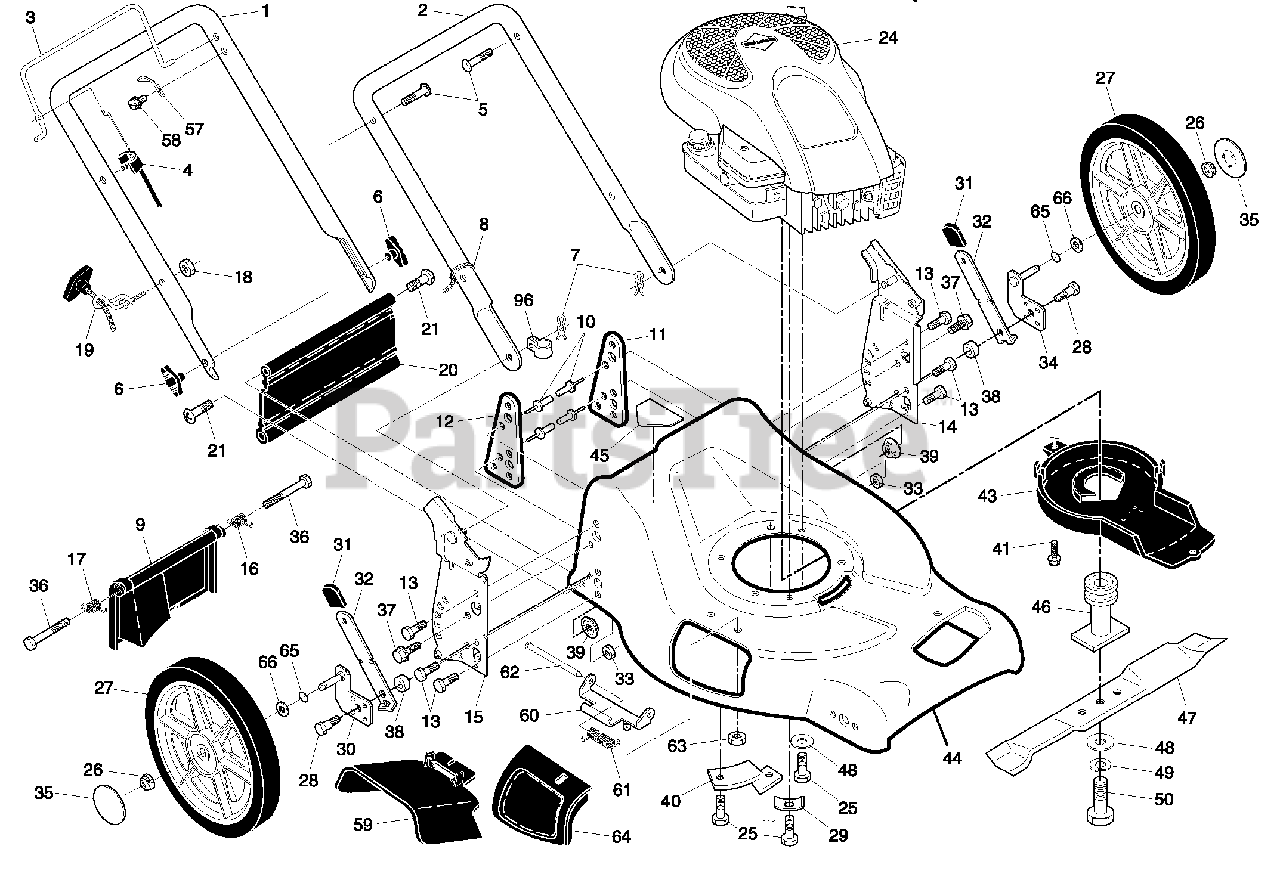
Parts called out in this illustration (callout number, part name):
1	Upper Handle
2	Lower Handle
3	Control Bar
4	Engine Zone Control Cable
5	Handle Bolt
6	Handle Knob
7	Hairpin Cotter
8	Wire Tie
9	Rear Door Assembly
10	Pop Rivet
11	Support Bracket, LH
12	Support Bracket, RH
13	Screw 1/4-20 x 5/8
14	Handle Bracket, LH
15	Handle Bracket, RH
16	Spring, Rear Door, LH
17	Spring, Rear Door, RH
18	Keps Locknut 1/4-20
19	Rope Guide
20	Rear Skirt
21	Hinge Screw 1/4-20 x 1-1/4
25	Screw, Hex Head, Threaded, Rolled 3/8-16 x 2
26	Nut, Hex, Flangelock 3/8-16
27	Wheel & Tire Assembly, Rear, 12"
28	Bolt, Shoulder 5/16-18
30	Axle Arm Assembly, Rear, RH
31	Selector Knob
32	Selector Spring
33	Nut, Hex, Nylock 5/16-18
34	Axle Arm Assembly, Rear, LH
35	Hubcap
36	Bolt, Rear Door
37	Thread Cutting Screw w/Sems 5/16-18 x 3/4
38	Washer, Flat .34 x 1.38
39	Nut, Hex
40	Mounting Bracket, Debris Shield
41	Screw, Debris Shield
43	Debris Shield
44	Kit, Housing
45	Danger Decal
46	Blade Adapter / Pulley
47	Blade, 21"
48	Hardened Washer
49	Helical Washer 3/8
50	Blade Bolt, Hex Head, Grade 8
57	Bracket, Upstop
58	Screw
59	Discharge Deflector
60	Hinge Bracket
61	Spring
62	Rod, Hinge
63	Nut, Hex
64	Mulcher Door
65	O-Ring
66	Washer, Flat 1/2
96	Clip, Cable
96	Operator's Manual, English
96	Operator's Manual, French
96	Repair Parts Manual
